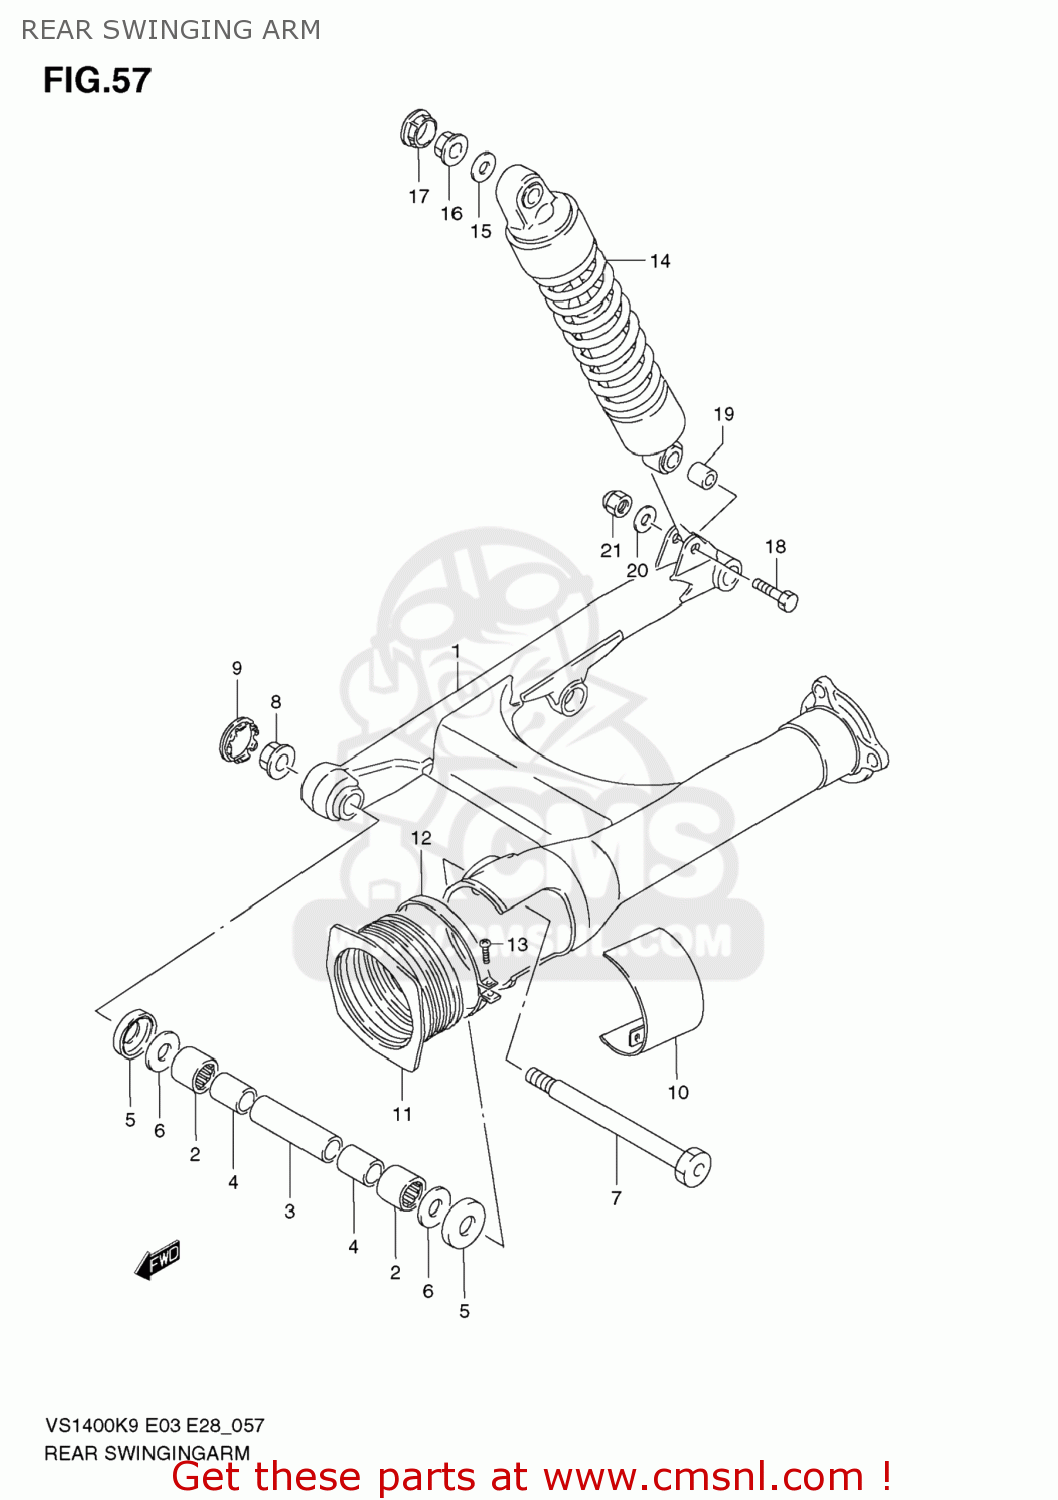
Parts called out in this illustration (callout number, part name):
1	SWINGINGARM,RR
2	BEARING(22X29X30)
3	SPACER,RR SWGARM PIVOT CTR
4	SPACER,RR SWGARM PIVOT
5	SEAL,RR SWGARM PIVOT DUST
6	WASHER
7	SHAFT,RR SWINGINGARM PIVOT
8	NUT
9	CAP,RR SWINGING ARM PIVOT,R
10	COVER,RR SWGARM PIVOT,L(GRAY)
11	BOOT,PROPELLER SHAFT
12	CLAMP
13	SCREW
14	ABSORBER ASSY,RR SHOCK
15	WASHER(10.5X20X2.3)
16	NUT
17	CAP,FRAME HANDLE GRIP
18	BOLT(10X39)
19	SPACER(10.2X14X20.7)
20	WASHER(10.5X24X2.3)
21	NUT
